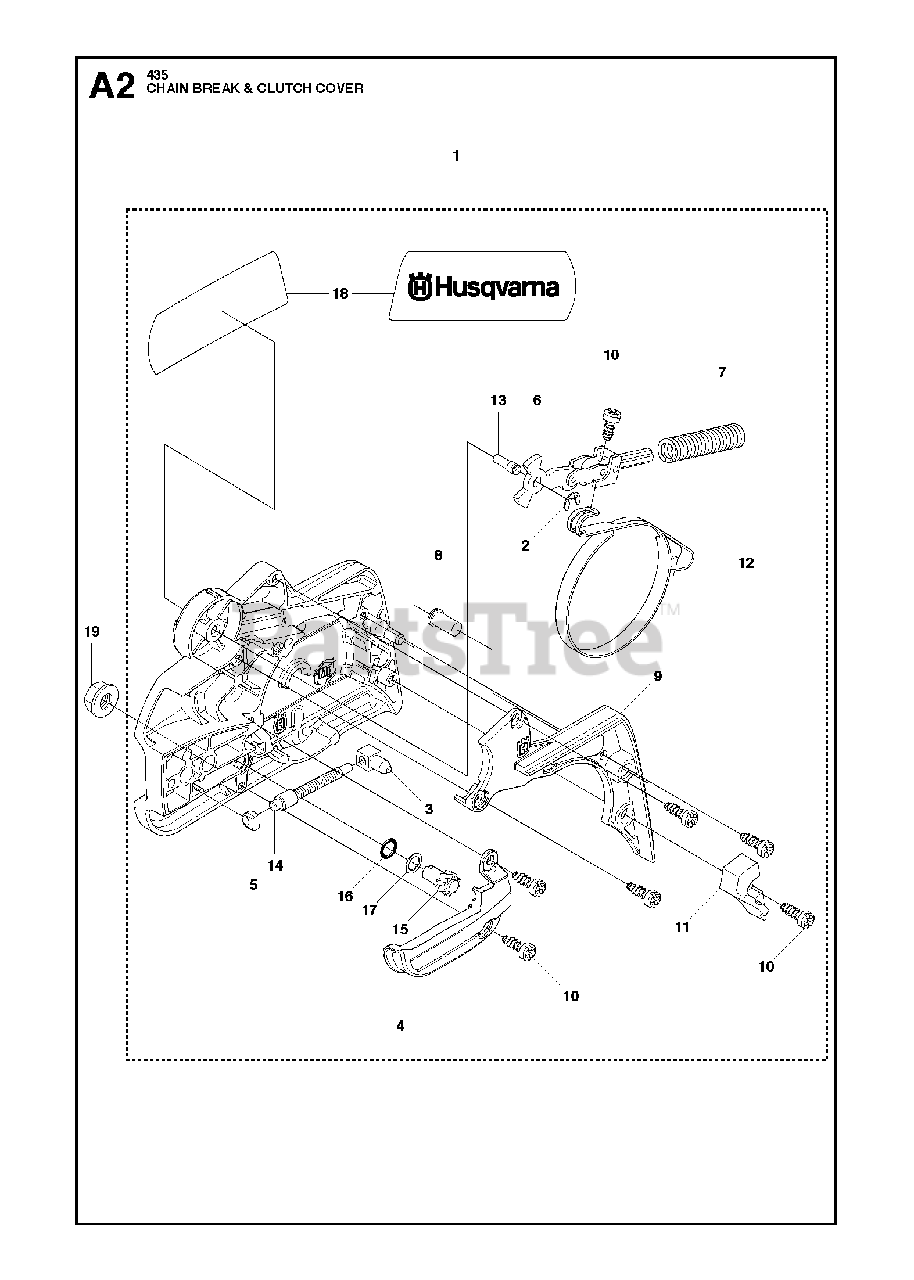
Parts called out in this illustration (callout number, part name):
1	CLUTCH COVER ASSY
2	E-RING 4
3	PAWL
4	CHAIN GUIDE
5	SLEEVE
6	JOINT
7	BRAKE SPRING
8	SLEEVE
9	COVER
10	SCREW
11	WEAR PROTECTION
12	BRAKE BAND ASSY
13	PIN
14	SCREW
15	WORM WHEEL
16	O-RING
17	WASHER
18	LABEL 400 SERIES
19	NUT M8 FLANGE
